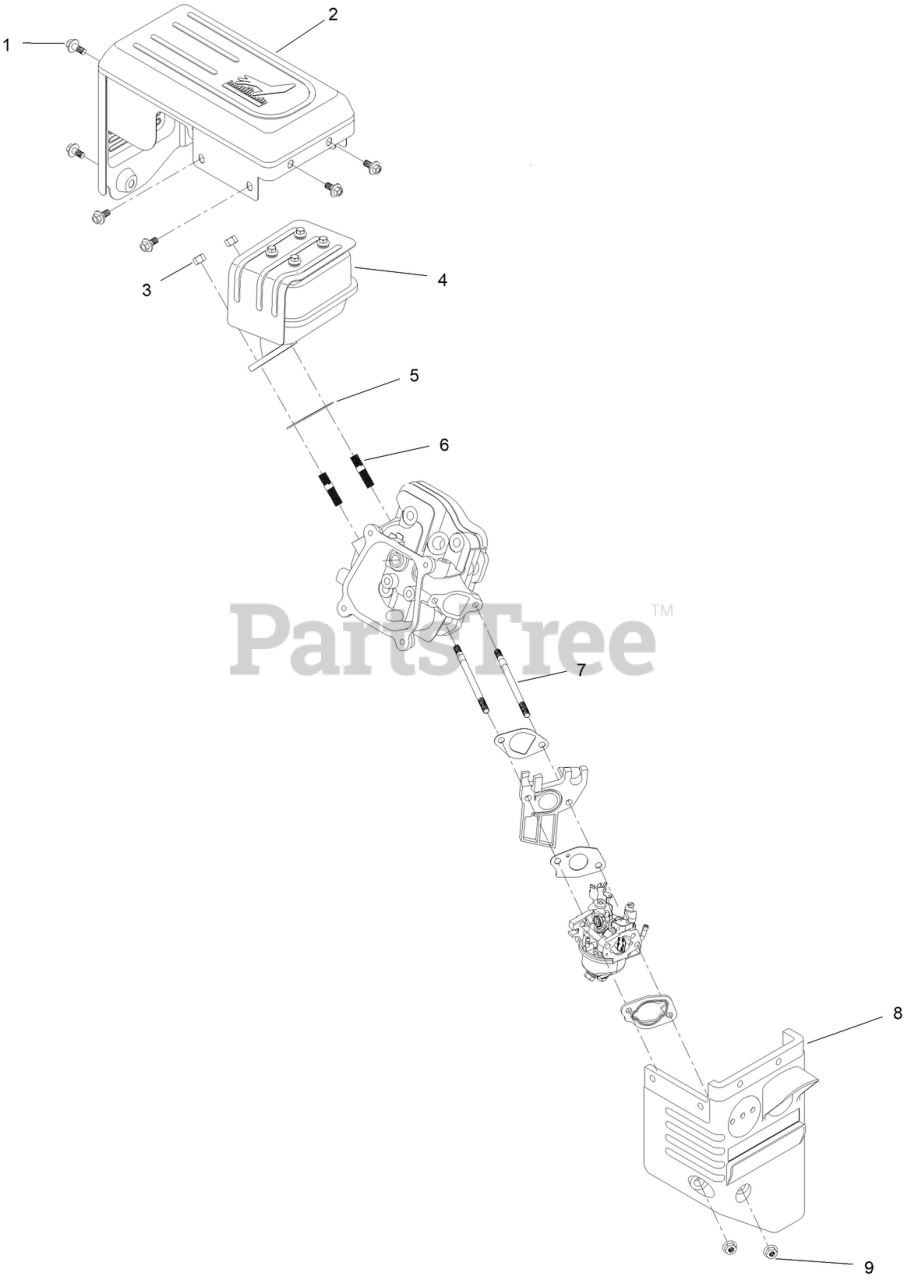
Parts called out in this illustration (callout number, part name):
1	SCREW-HHF
2	GUARD-MUFFLER
3	NUT-HH
4	MUFFLER ASM
5	GASKET-EXHAUST
6	STUD-EXHAUST
7	STUD-INTAKE
8	BOX-HEATER
9	NUT-FLANGE
